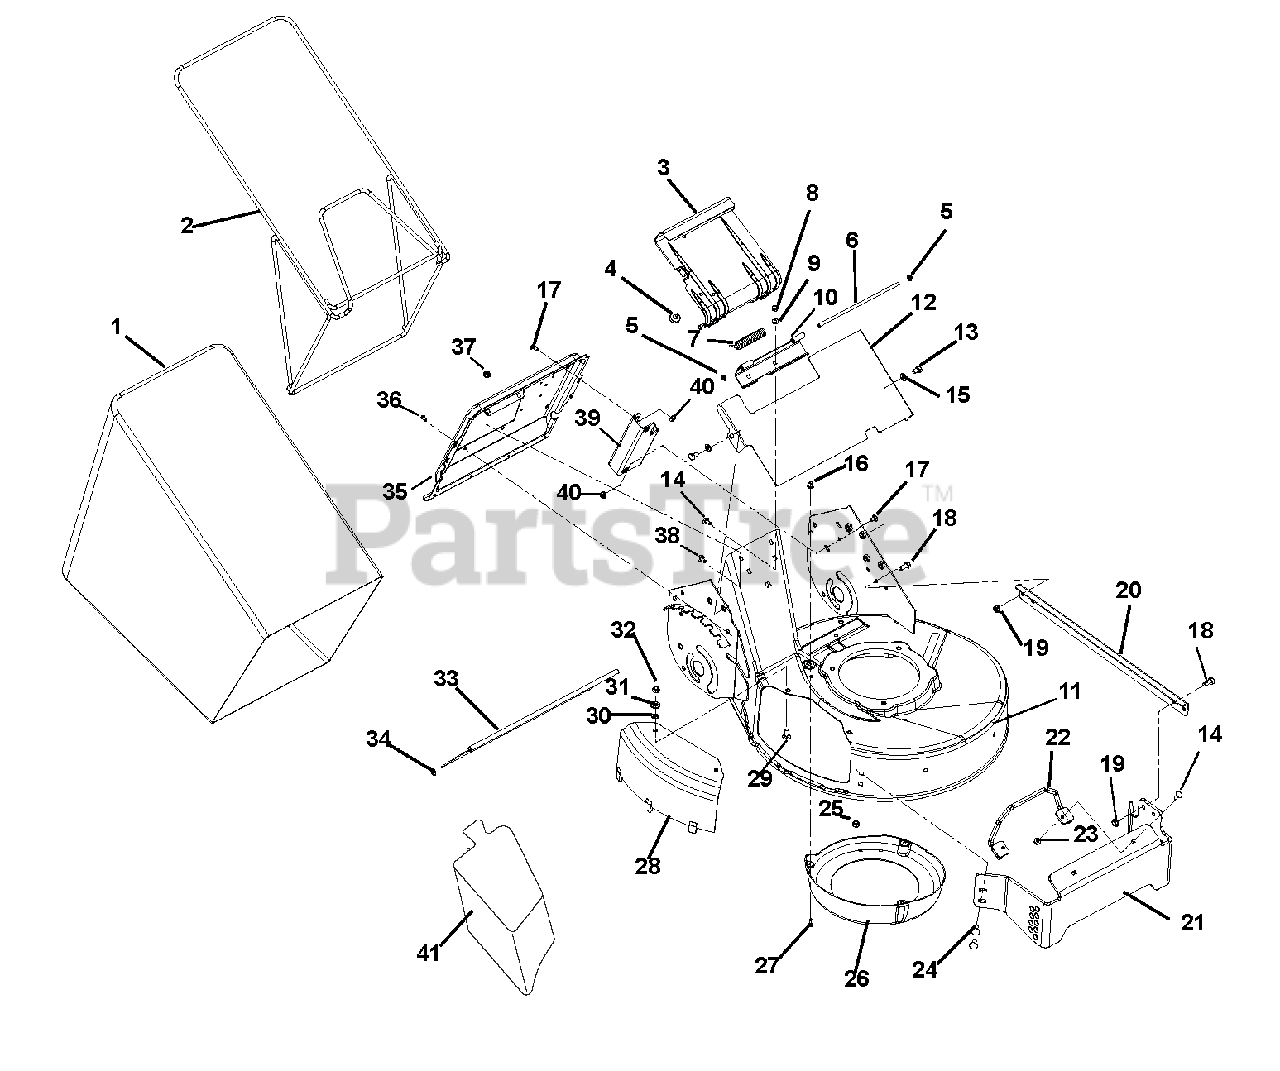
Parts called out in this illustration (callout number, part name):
1	BAG, CONSUMER BLACK 15 OZ/YD2
2	FRAME, WBLM BAGGER
3	CATCHER PLATE DOOR
4	BUTTON BUMPER
5	PUSH NUT, .25
6	DOOR PIN
7	SG-TORS .120X.68X3.09
8	@NUT-HEX .25-20 YWZC
9	WSHR-LK .250X.077 HVY YWZC
10	HINGE BASE
11	CHASSIS,PRO 21 XD
12	COVER
13	@SCR-TAP .25-20X.37 HWH YWZ TR
14	@BLT-RDHDSQNK .25-20X.75 G5YZ
15	@WSHR-LK .31X.078 REG YWZC
16	PLASTIC GROMMET
17	@BLT-RDHDSQNK .25-20X.50 G5YZ
18	@BLT-HEX .31-18X.75 GR5 YWZC
19	@NUT-LK-TOP-FLG .31-18 YWZC
20	ANGLE-SUPPORT
21	BUMPER,PRO 21"
22	ANGLE-SUPPORT
23	@NUT-LK-TOP-FLG .25-20 YWZC
24	@BLT-RDHDSQNK .31-18X.75 G5YZ
25	@NUT-SPNLK-FLG .312-18 YWZC
26	CENTER BAFFLE
27	SCR-TAP 10-16X.62 SLPH AB YWZC
28	COVER, SIDE DISCHARGE
29	BLT-RDHDSQSHK.31-18X.75 GR2 YW
30	NUT-PUSH .312
31	@WSHR-FL-STL.406X.812X.065 YWZ
32	@NUT-LK-NYL .312-18 YWZC
33	TRAILING SHIELD
34	NUT-PUSH .312
35	CATCHER PLATE
36	SCR-TAP 10-24X.375 TORX PHD YZ
37	@NUT-SPNLK-FLG .25-20 YWZC
38	@BLT-RDHDSQNK .25-20X.50 G5YZ
39	BKT,BAGGER SUPPORT
40	@NUT-SPNLK-FLG .25-20 YWZC
41	MULCH MASTER MULCHER ACCESSORY
